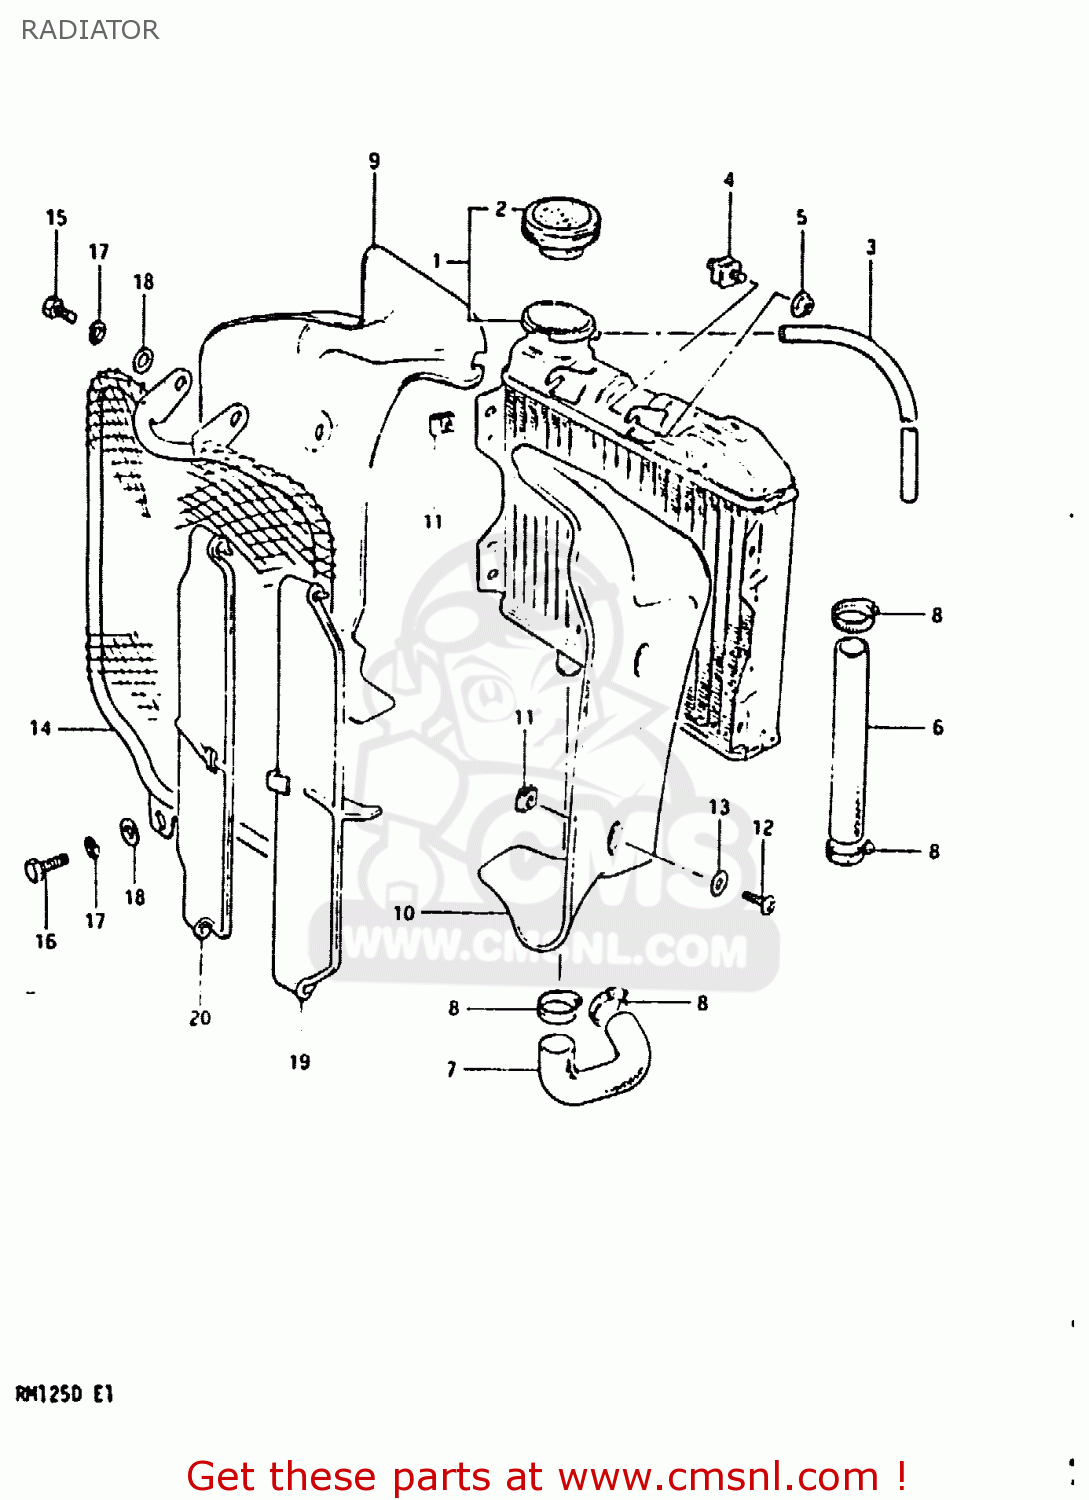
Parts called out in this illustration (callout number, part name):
1	RADIATOR ASSEMBLY,WATER
2	CAP,RADIATOR
3	HOSE,BREATHER
4	CUSHION,RADIATOR
5	NUT
6	HOSE,RADIATOR
7	HOSE,RADIATOR OUTLET
8	CLAMP
9	COVER,RADIATOR,R
10	COVER,RADIATOR,L
11	PLATE,RADIATOR COVER F
12	SCREW
13	WASHER (6.5X18X1.6)
14	BUMPER,RADIATOR
15	BOLT
16	BOLT
17	LOCK WASHER
18	WASHER,8.5X16X
19	LOUVER,RADIATOR MUD GUARD
20	LOUVER, MUDGUARD INNER
